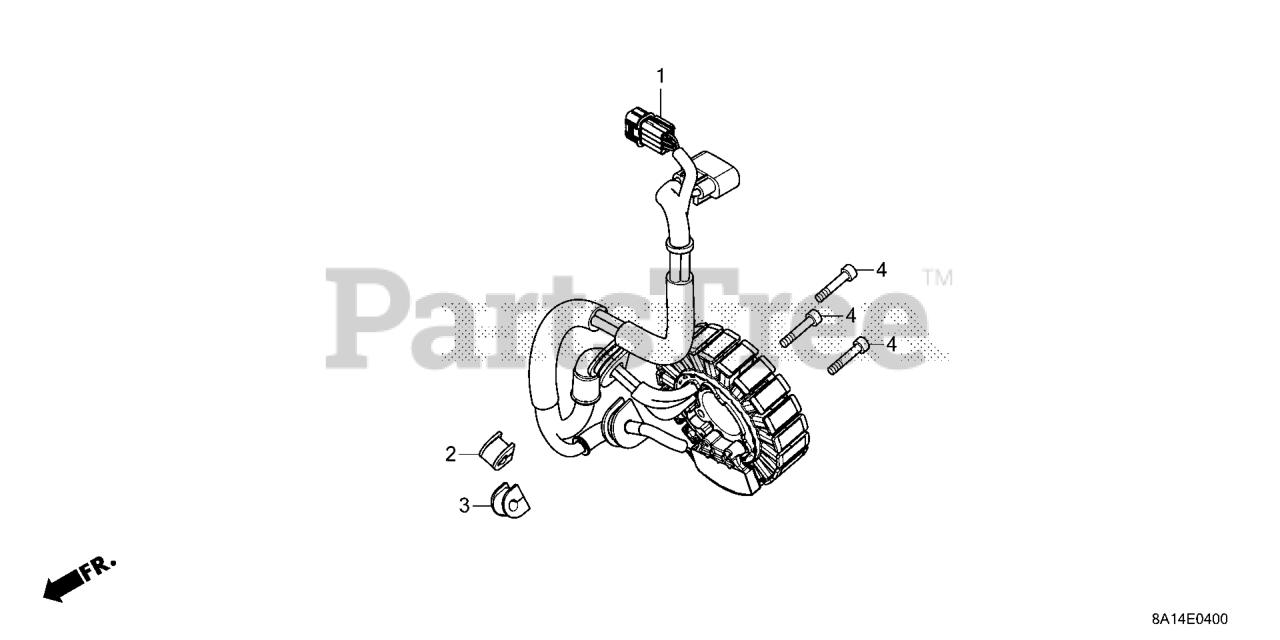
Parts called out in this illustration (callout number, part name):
1	STATOR ASSY.
2	GROM, MOTOR HARNESS
3	GROM, SENSOR HARNESS
4	BOLT, SOCKET (6X40)
